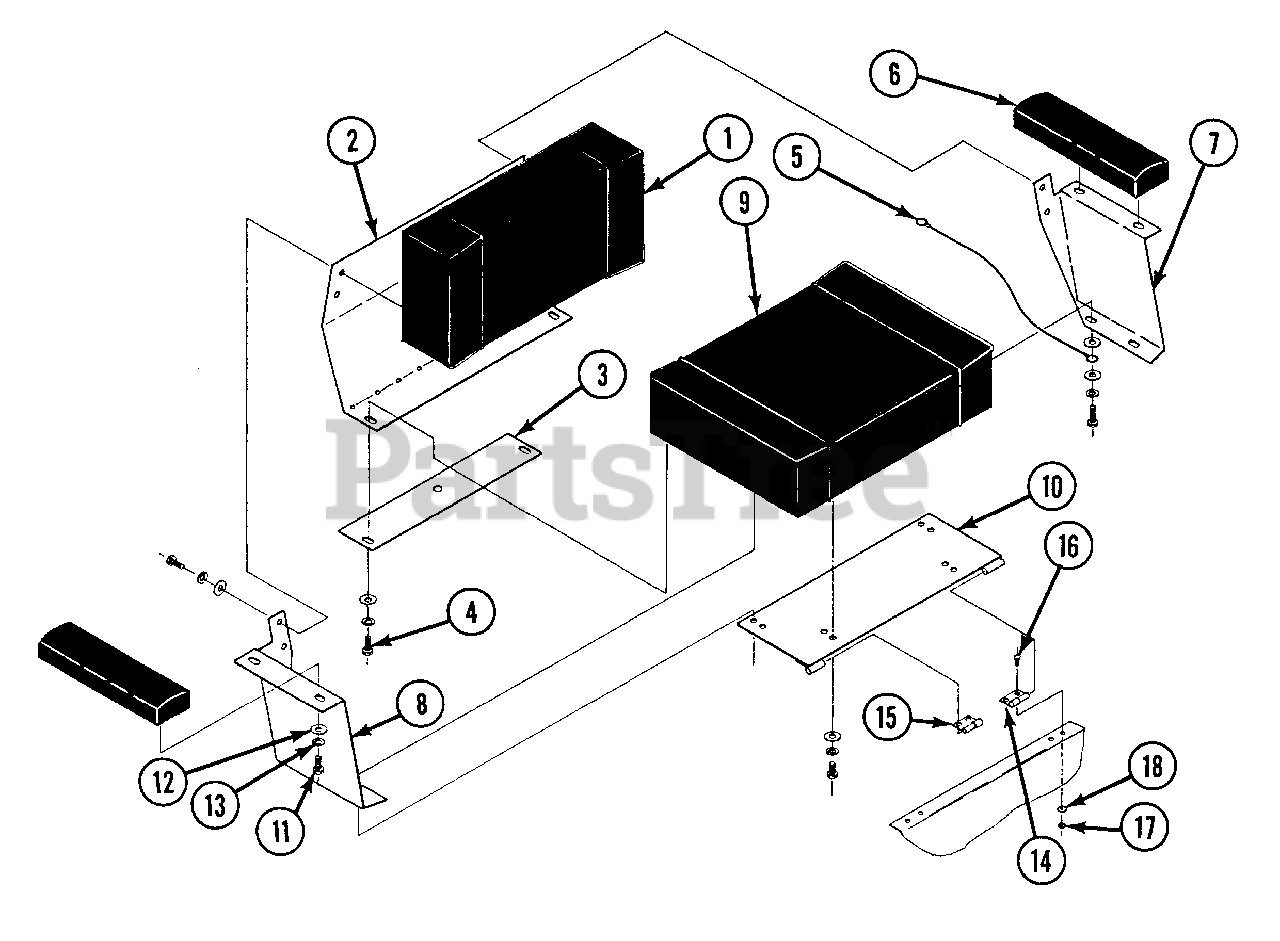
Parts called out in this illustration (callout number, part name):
1	BACK CUSHION ASSEMBLY
2	BACK REST COVER
3	ACTUATOR WELDMENT, SEAT SWITCH
4	CAPSCREW, HX HD: 5/16-18 X 1 GR 5
5	CABLE ASSEMBLY, SEAT
6	ARM CUSHION ASSEMBLY
7	ARM SUPPORT LEFT
8	ARM SUPPORT RIGHT
9	SEAT CUSHION ASSEMBLY
10	SEAT HINGE WELDMENT
11	CAPSCREW, HX HD: 5/16-18 X 3/4 GR 5
12	FLAT WASHER: 5/16
13	LOCKWASHER, SPLT SPRNG: 5/16
14	SEAT HINGE, LH
15	SEAT HINGE, RH
16	CAPSCREW, HX HD: 1/4-20 X 5/8 GR 5
17	LOCKNUT, NYLOCK: 1/4-20
18	FLAT WASHER: 1/4
